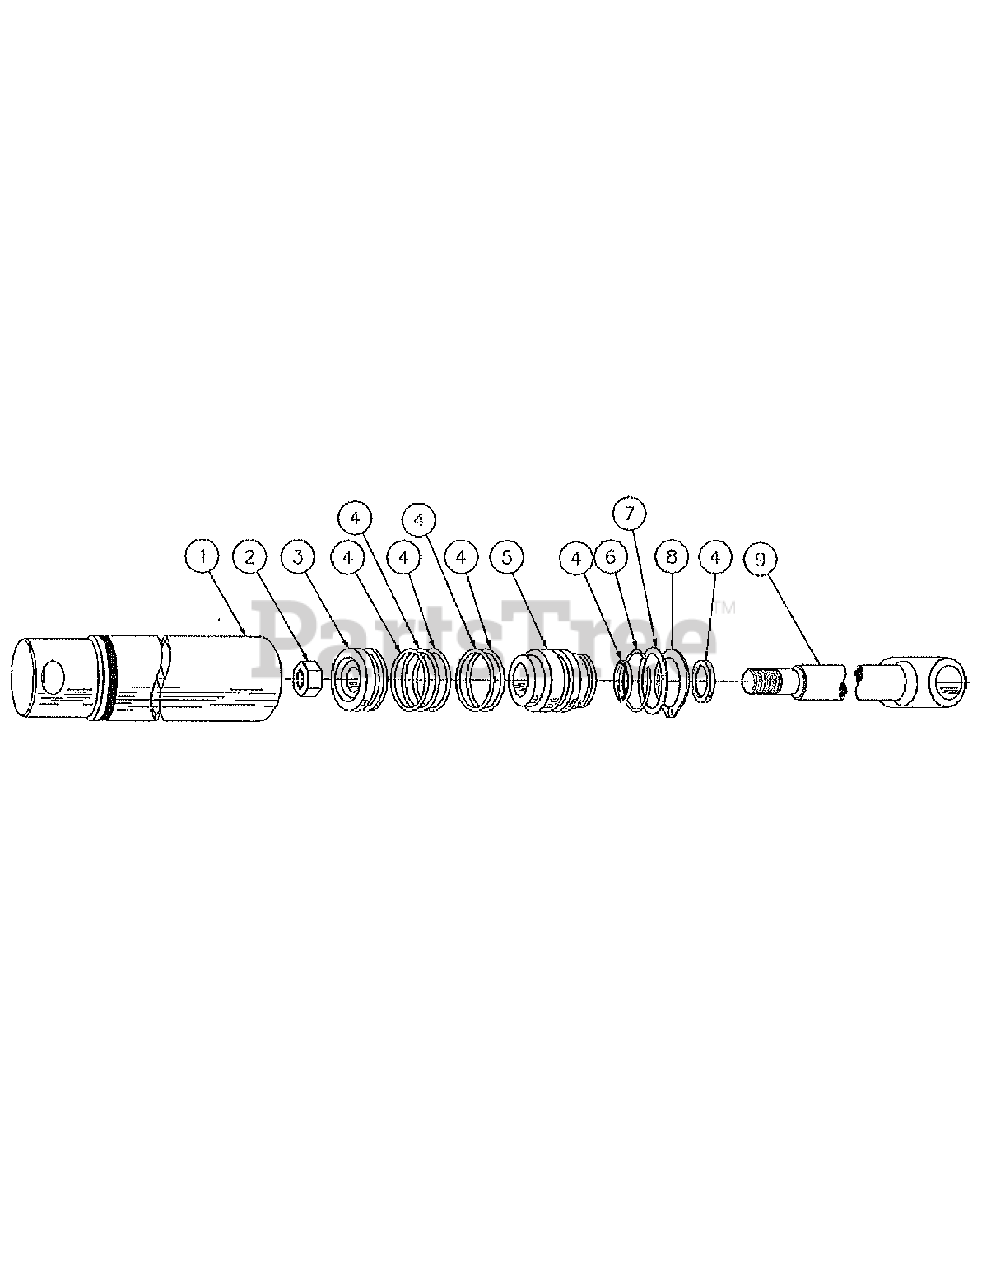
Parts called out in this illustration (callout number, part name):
1	Tube Assembly, RH
6	Retaining Ring
8	Retaining Ring
9	Rod Assembly, RH
